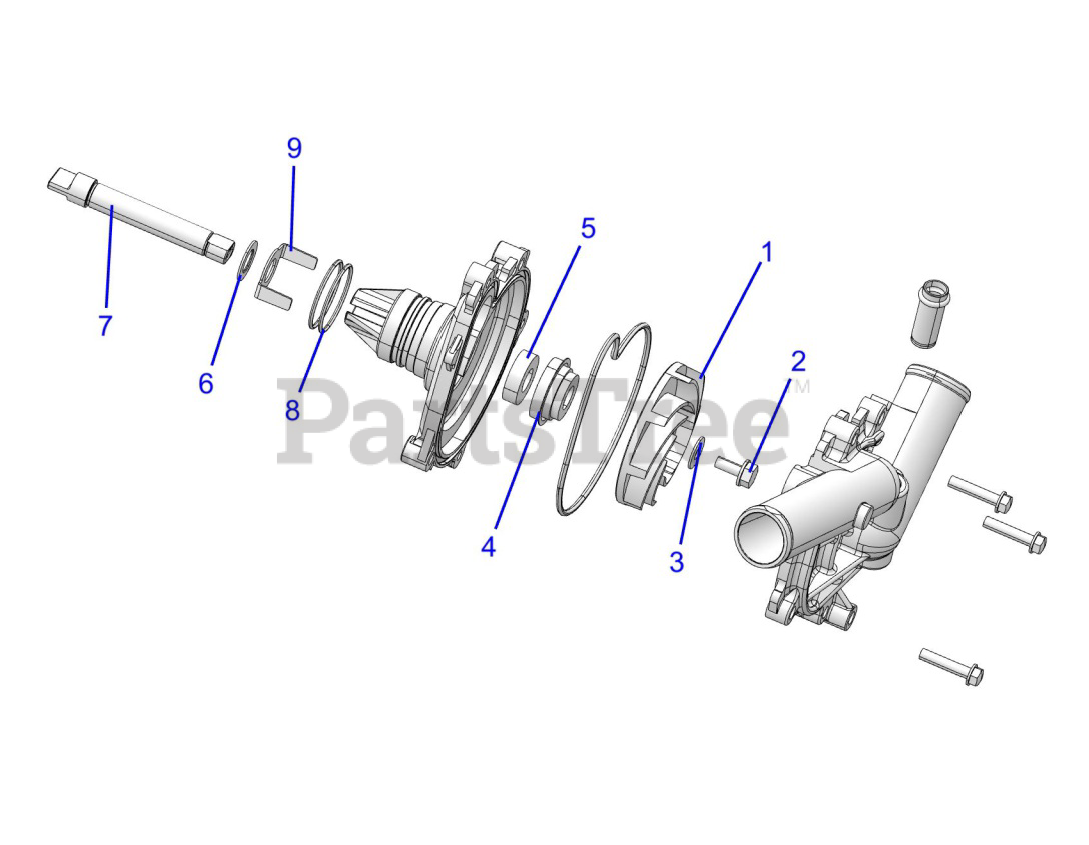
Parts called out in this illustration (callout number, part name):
1	IMPELLER, WATERPUMP
2	SCREW
3	WASHER, IMPELLER
4	SEAL, WATERPUMP SHAFT, MECHANICAL
5	SEAL, WATERPUMP SHAFT, OIL
6	WASHER, WATERPUMP, RETAINER
7	SHAFT, WATERPUMP,
8	O-RING
9	WASHER, WATERPUMP,RETAINER
